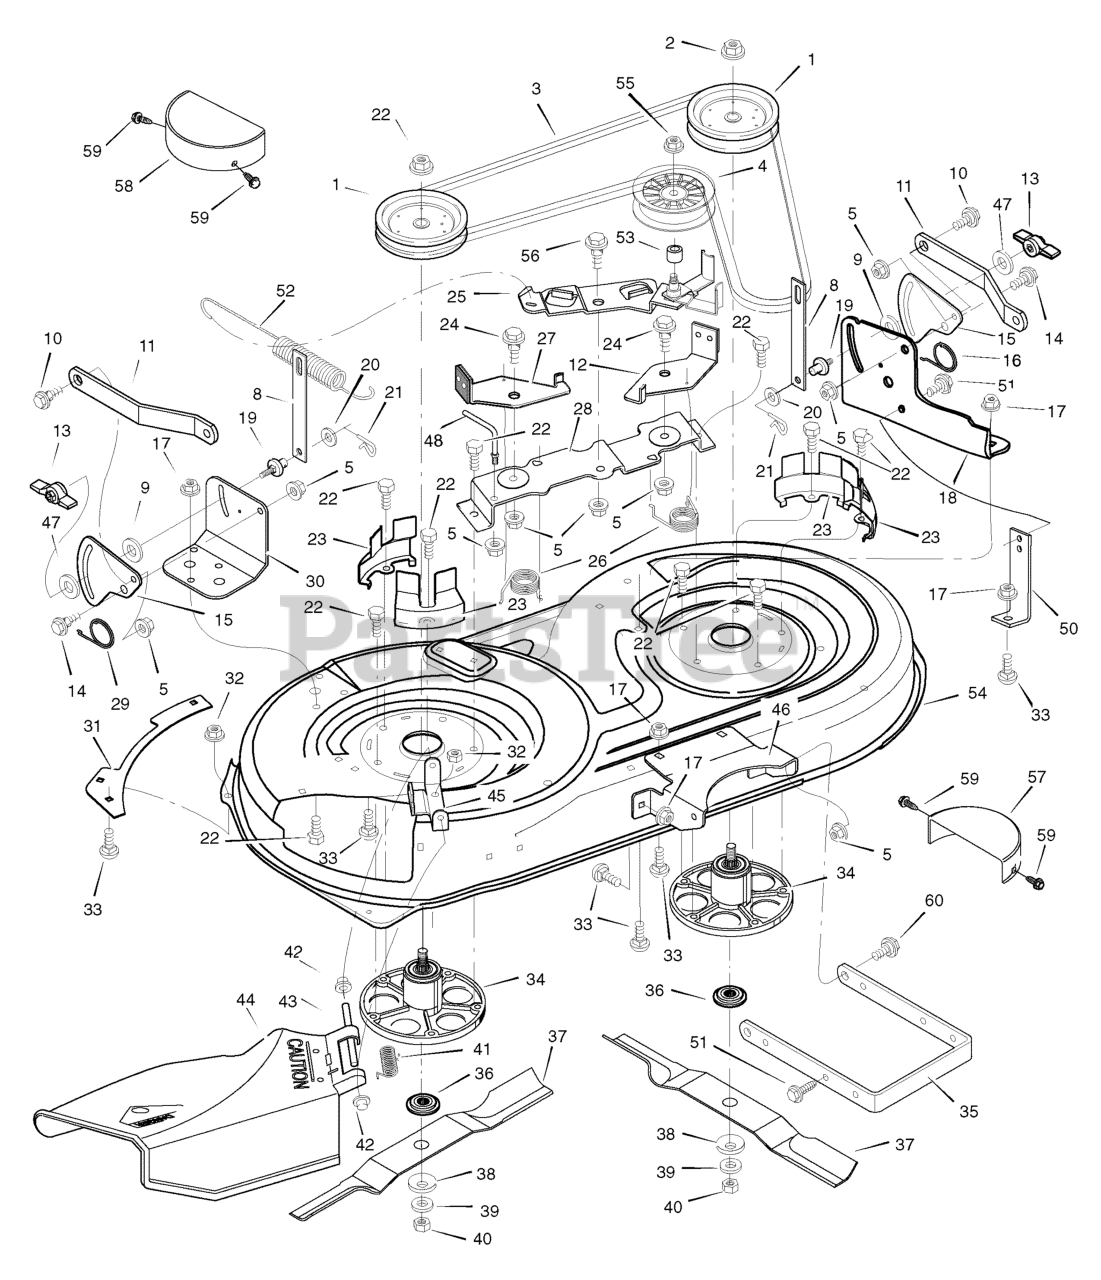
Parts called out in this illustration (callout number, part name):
1	Pulley, Jackshaft
2	Nut, Hex
3	Belt, Mower Drive
4	Pulley, Idler
5	Nut, Flange
8	Link, Lift
9	Pad, Friction
10	Bolt, Shoulder
11	Bracket, Suspension
12	Pad Assembly, Left Brake
13	Knob
14	Bolt, Shoulder
15	Plate, Suspension
17	Nut, Flange
18	Bracket, Suspension
19	Pin, Hanger
21	Pin, Cotter
22	Bolt 3/8 x 1"
23	Cover, Pulley
24	Bolt, Shoulder
25	Arm, Idler
27	Pad Assembly, Right Brake
28	Bracket Assembly, Brake
30	Bracket, Suspension
32	Nut, Flange
33	Bolt, Carriage
34	Mandrell
35	Bracket, Suspension
36	Adapter, Blade
42	Cap, Push On
43	ROD, Deflector
44	Deflector Assembly
45	Bracket, Deflector
46	Bracket, Front Hanger
48	Guide, Belt
50	Bracket, Support
52	Spring, Extension
54	Housing, Blade
55	Nut, Flange
56	Bolt, Shoulder
57	COVER, Pulley L.H.
58	GUARD, Belt R.H.
60	Bolt, Shoulder
